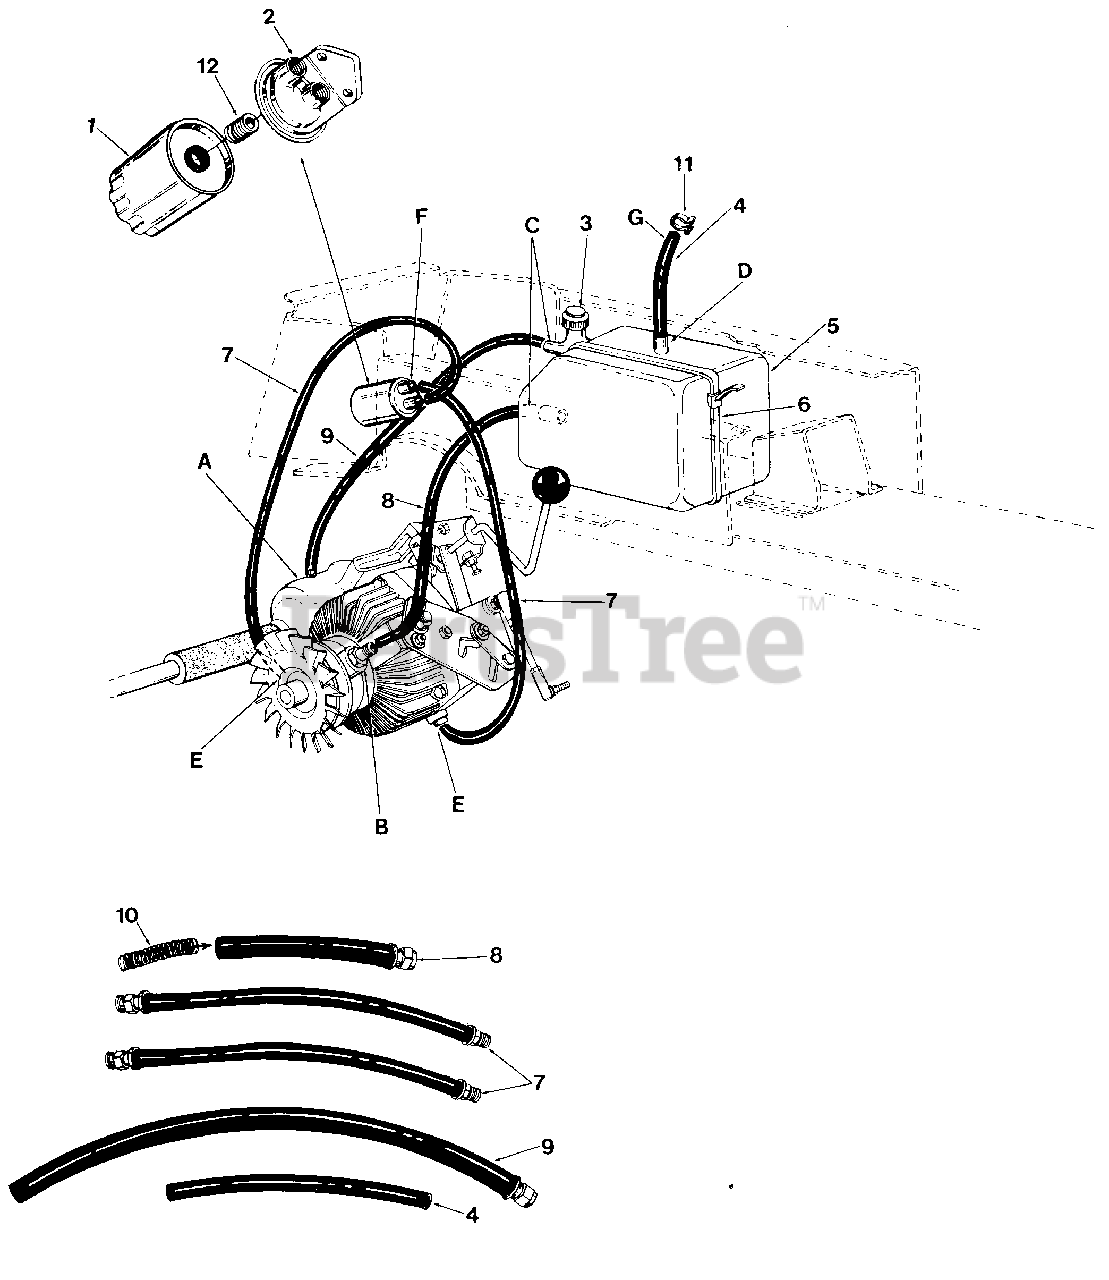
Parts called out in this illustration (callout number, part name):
1	Oil Filter
2	Filter Base
3	Oil Reservoir Cap
4	Gas Line 13" Lg.
5	Oil Reservoir
6	Cable Tie 34.25" Lg.
7	Hose Ass'y. 3/8 I.D. x 16.5" Lg.
8	Hose Ass'y. 5/8" I.D. x 9" Lg.
9	Hose Ass'y. 1/2" I.D. x
10	Spring Part of Ref. No. 8
11	Wire Retainer
12	Expansion Plug 1 3/16"
A	7/8-14 SAE Boss to 3/4-16 JIC.
B	Boss to Male JIC.
C	Hose Clamp 1.25 x .66 I.D>
D	Hose Clamp .406" Dia.
E	1/2-40 SAE Boss to 1/2 20
F	Pipe Reducer 1/2-14 to 3/8 18 NPT
G	Hose Clamp .37" Dia.
